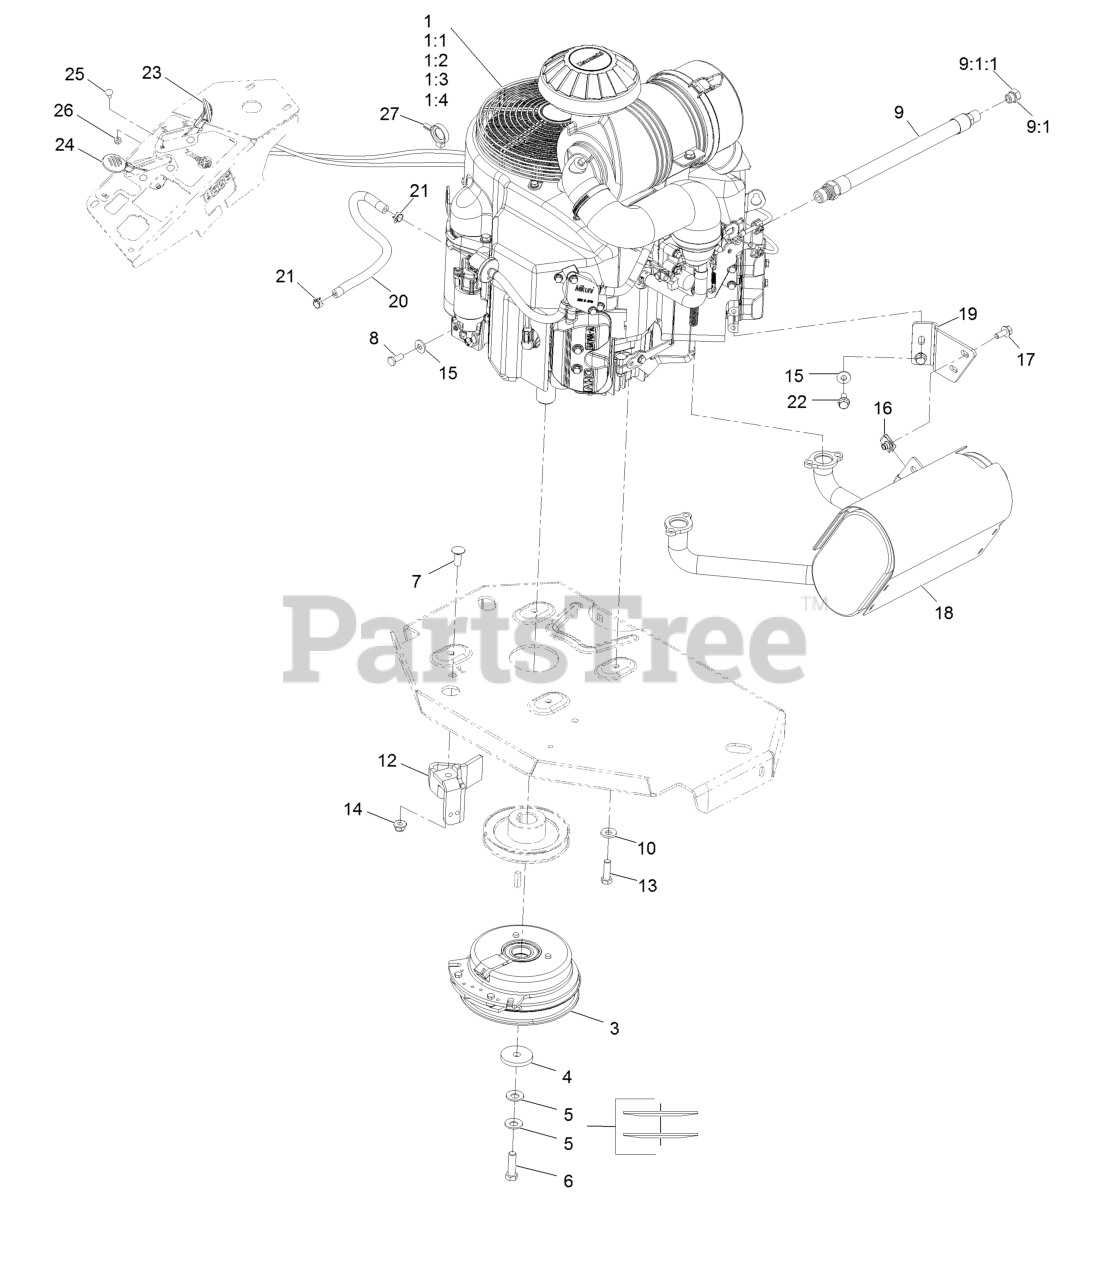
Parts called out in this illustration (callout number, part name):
1:1	Kawasaki 49065-2078 Engine Oil Filter
1:2	Kawasaki 49019-7001 Fuel Filter
1:3	Kawasaki 11013-7039 Safety Filter
1:4	Kawasaki 11013-7038 Air Filter
3	Clutch Kit
4	Washer-Clutch
5	Washer-Spring Disc 7/16
6	Screw-HH 7/16-20 X 1 1/2 W/Loctite
7	Bolt-Carriage 3/8-16 X 1
8	Screw-HH M8-1.25 X 20Mm
9	Asm-Hose Oil Drain W/Plug
9:1	Plug-W/O-Ring
9:1:1	O-Ring
10	Washer-Spring Disc 3/8
12	Clutch-Anchor
13	Screw-HH 3/8-16 X 1 1/4
14	Nut-Nyloc 3/8-16 Flg
15	Washer-Spring Disc 5/16
17	Screw-HH Flg 5/16-18 X 3/4
18	Muffler
19	Bracket-Muffler
20	Hose-Fuel Line 15"
21	Clamp-Hose
22	Screw-HH M8-1.25 X 20Mm
23	ASM, Choke Cable
24	ASM,Throttle Cable
25	Bolt-Carriage #10-24 X 1/2
26	Nut-Nyloc #10-24
27	Clamp-Hose
